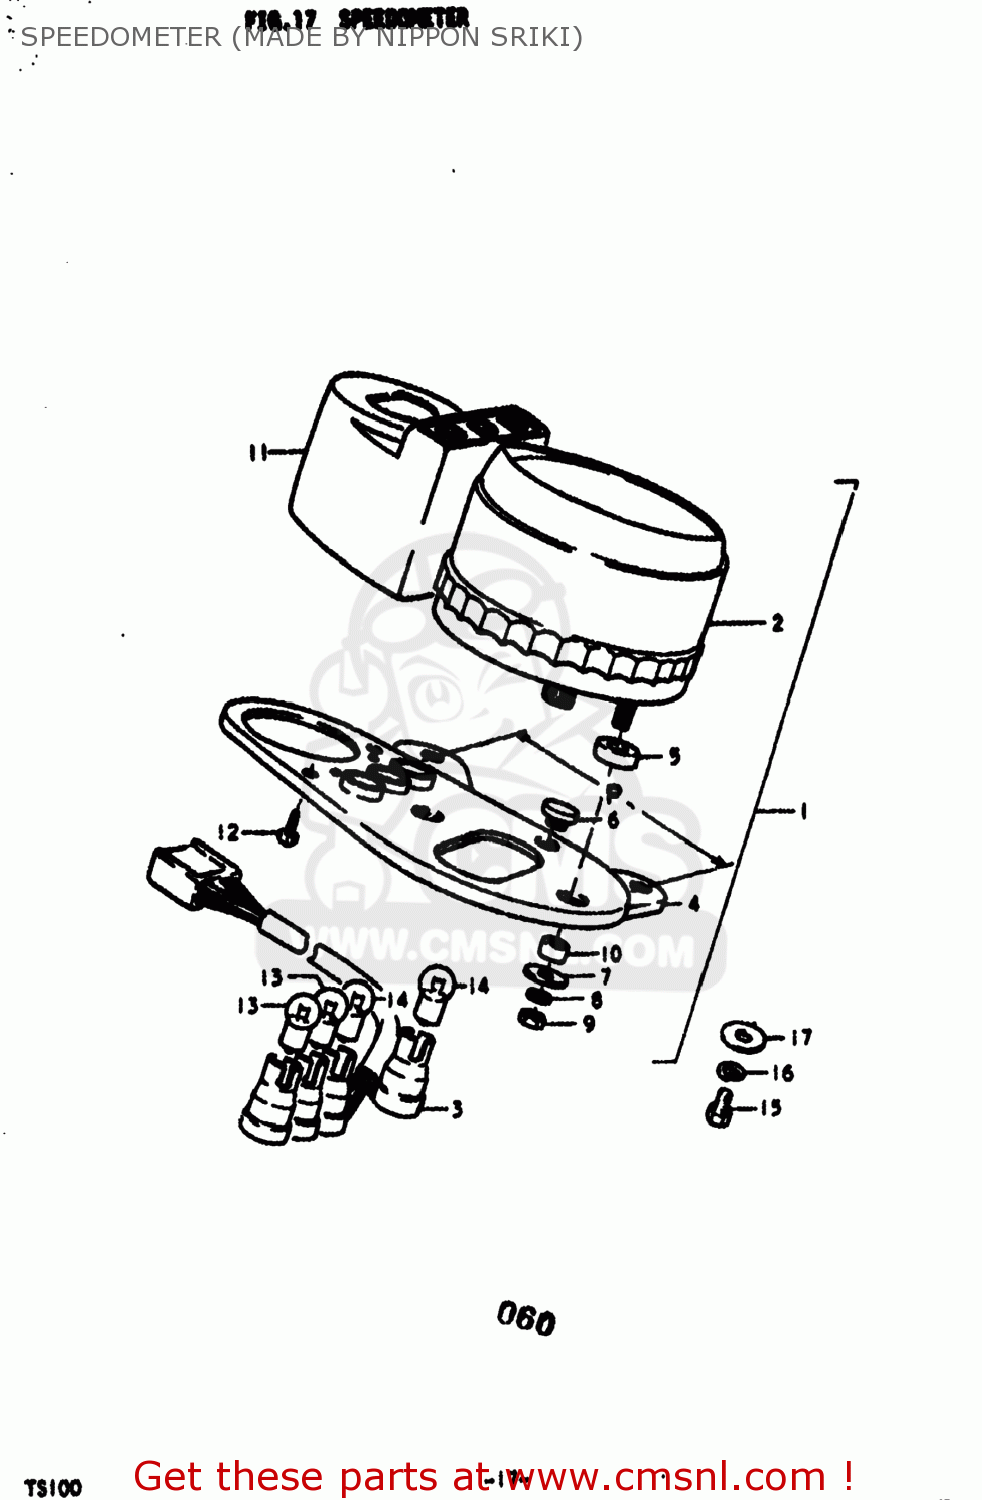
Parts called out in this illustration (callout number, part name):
1	SPEEDOMETER ASSEMBLY
2	SPEEDOMETER ASSEMBLY
3	SOCKET,METER
4	BRACKET,METER
5	CUSHION,METER NO.1
6	CUSHION,METER
7	WASHER
8	LOCK WASHER
9	NUT
10	SPACER,METER
11	CASE,PILOT BULB
12	SCREW
13	BULB(6V1.7W,STANLEY,A61A)
14	BULB(6V/3W)
15	BOLT
16	LOCK WASHER
17	WASHER 6MM
